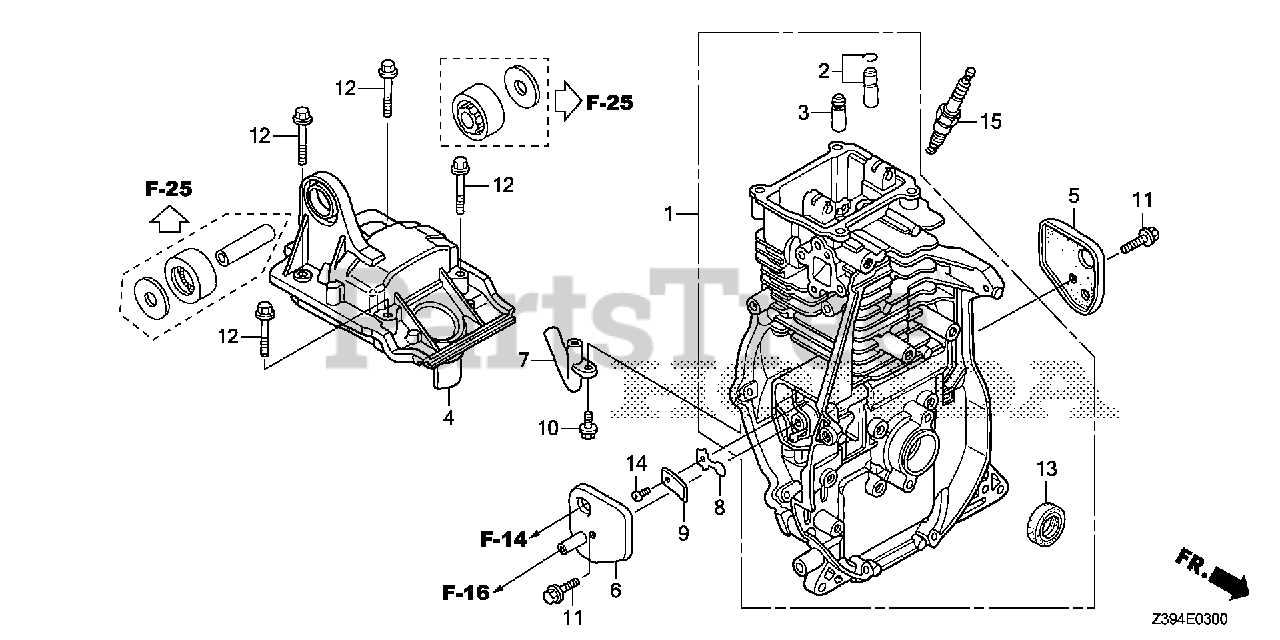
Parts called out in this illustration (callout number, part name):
1	CYLINDER ASSY.
2	GUIDE ASSY., EX. VALVE (OVER SIZE)
3	GUIDE, VALVE (OVER SIZE)
4	COVER, HEAD
5	COVER A, BREATHER
6	COVER B, BREATHER
7	PIPE, BREATHER
8	VALVE, OIL OUTLET
9	PLATE, STOPPER
10	BOLT (4X10)
11	BOLT, FLANGE (6X14) (CT200)
12	BOLT, FLANGE (6X28) (CT200)
13	OIL SEAL (20X32X6)
14	SCREW, PAN (3X5)
15	SPARK PLUG (CR4HSB)
15	SPARK PLUG (CR5HSB)
